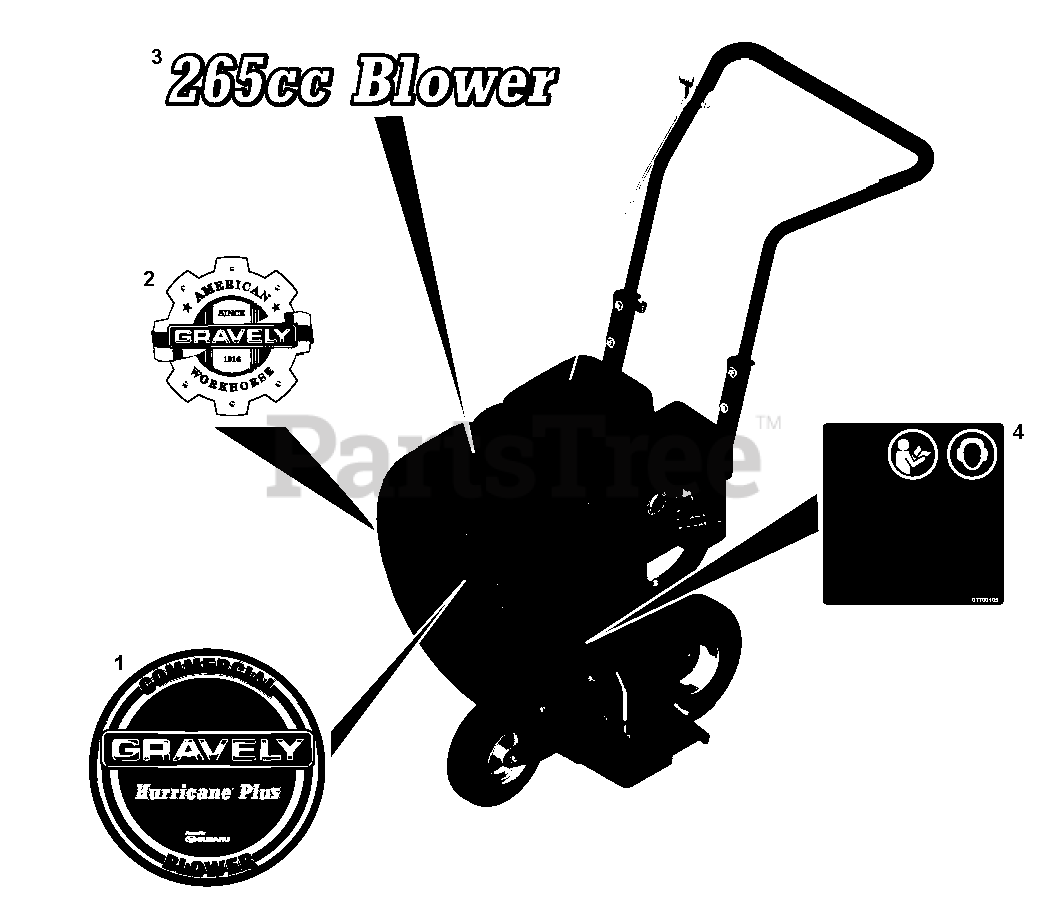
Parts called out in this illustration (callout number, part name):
1	DECAL - BLOWER, 9" RD GRAVELY
2	DECAL, GRAVELY HERITAGE-SMALL
3	DECAL-P BLOWER, 169CC
4	DECAL,BLOWER WARNING ISO
